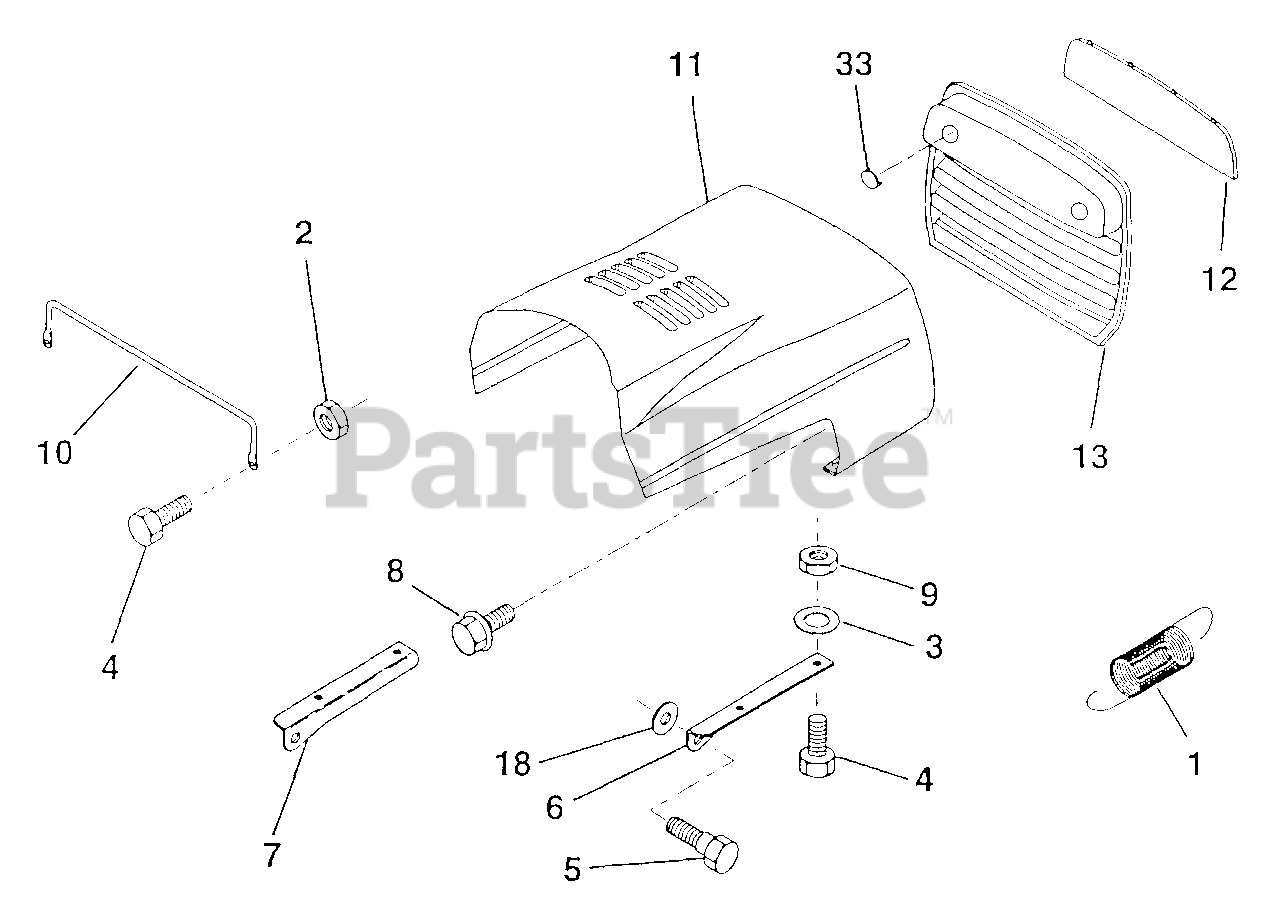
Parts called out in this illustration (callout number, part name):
1	Extension, Spring
2	Nut, Hex, Keps 1/4-20
3	Washer, 9/32 x 7/8 x 16 Ga.
4	Bolt, Hex Fin 1/4-20 x 3/4 Gr. 5 (AYP part number)
5	Bolt, Shoulder
6	Bracket, Hood R.H.
7	Bracket, Hood L.H.
8	Screw Sltd. Hex Hd W/PL Washer
9	Nut Lock W/Insert 1/4-20 UNC
10	Brace, Hood
12	Lens Clear Bar
13	Grille
18	Washer 11/32 x 11/16 x 16 Ga.
20	Plug, Socket Light (AYP part number)
